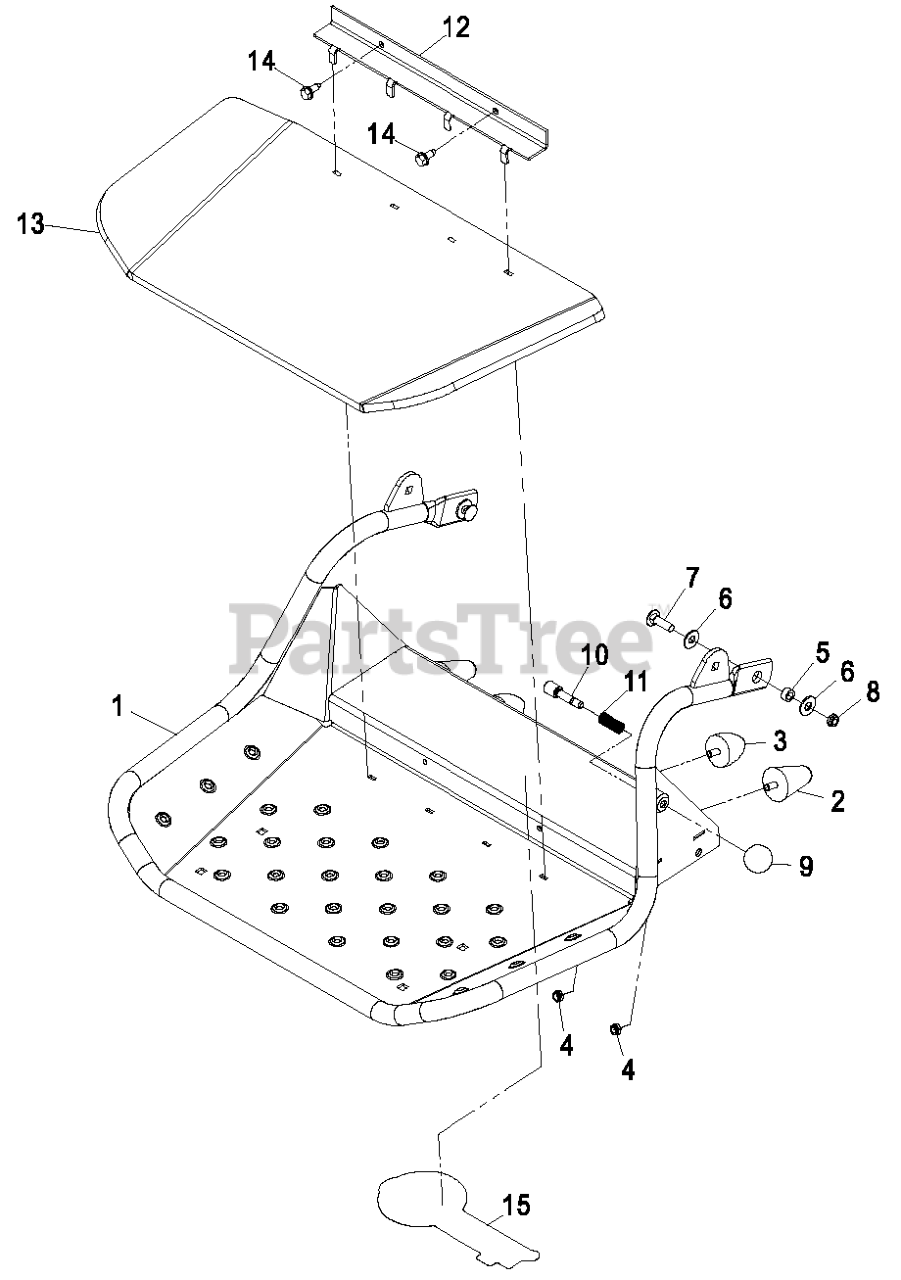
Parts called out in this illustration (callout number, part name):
1	PLATFORM ASM
2	BUMPER-RUBBER
3	BUMPER-RUBBER
4	NUT-LOCK, NI
5	SPACER
6	WASHER-FLAT
7	BOLT-CARR
9	KNOB-BALL
12	CLAMP-SHIELD
14	Screw-HWH 5/16-18 X 3/4 Tf
15	DECAL, EXMARK LOGO
